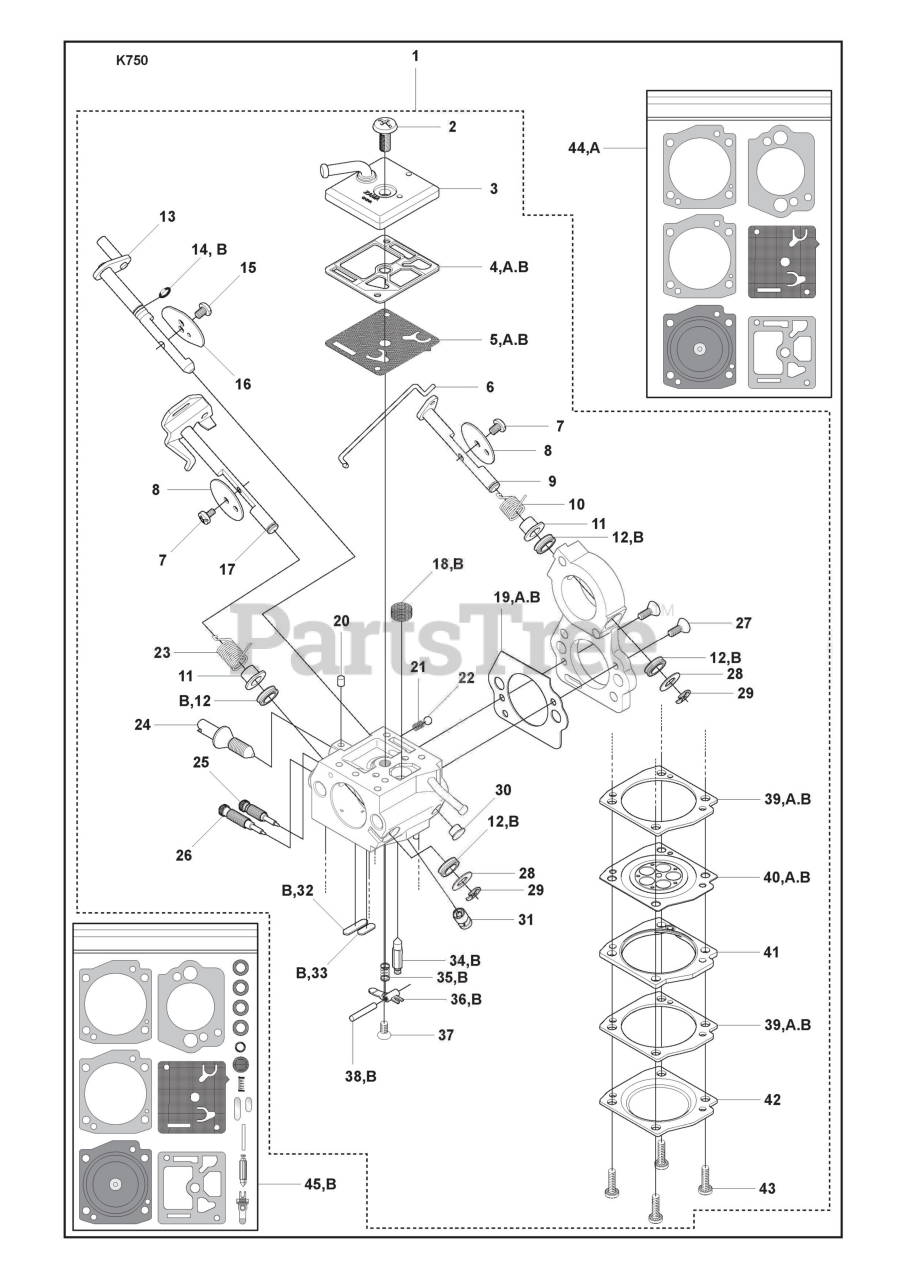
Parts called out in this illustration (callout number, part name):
1	CARBURETTOR
3	PUMP COVER
4	GASKET PUMP
5	DIAPHRAGM PUMP
9	SHAFT ASSY
13	SHAFT ASSY CHOKE
17	SHAFT ASSY
31	NOZZLE ASSY
32	PLUG WELCH
38	PIN RETAINING SCREW
40	DIAPHRAGM ASSY
44	GASKET KIT
45	GASKET KIT CARB
